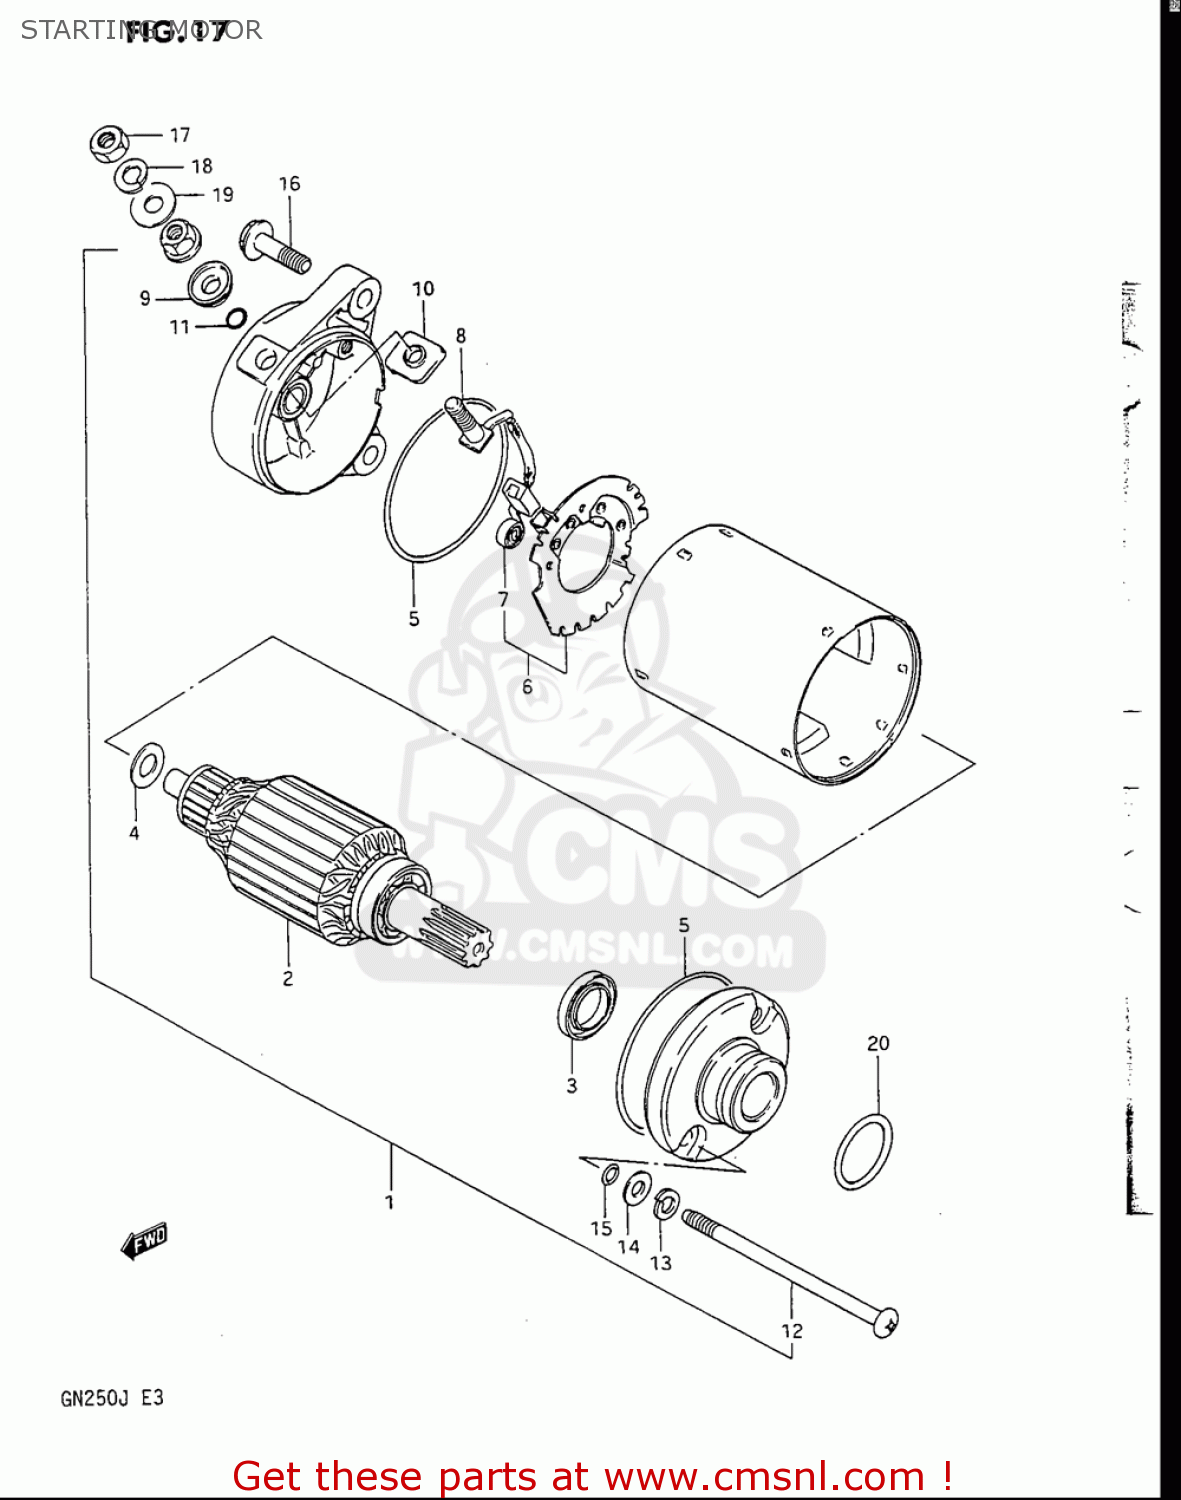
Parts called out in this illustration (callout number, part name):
1	MOTOR ASSY,STARTING
2	ARMATURE
3	SEAL,OIL
4	SHIM SET,STARTING MOTOR
5	O RING
6	HOLDER,BRUSH
7	SPRING
8	BRUSH SUB ASSY,STARTING MOTOR
9	BUSHING
10	BUSH,B
11	O RING
12	BOLT
13	WASHER,LOCK
14	WASHER
15	O RING
16	BOLT
17	NUT
18	WASHER,LOCK
19	WASHER(6.5X16X1)
20	O RING(D:3,ID:24.5)
